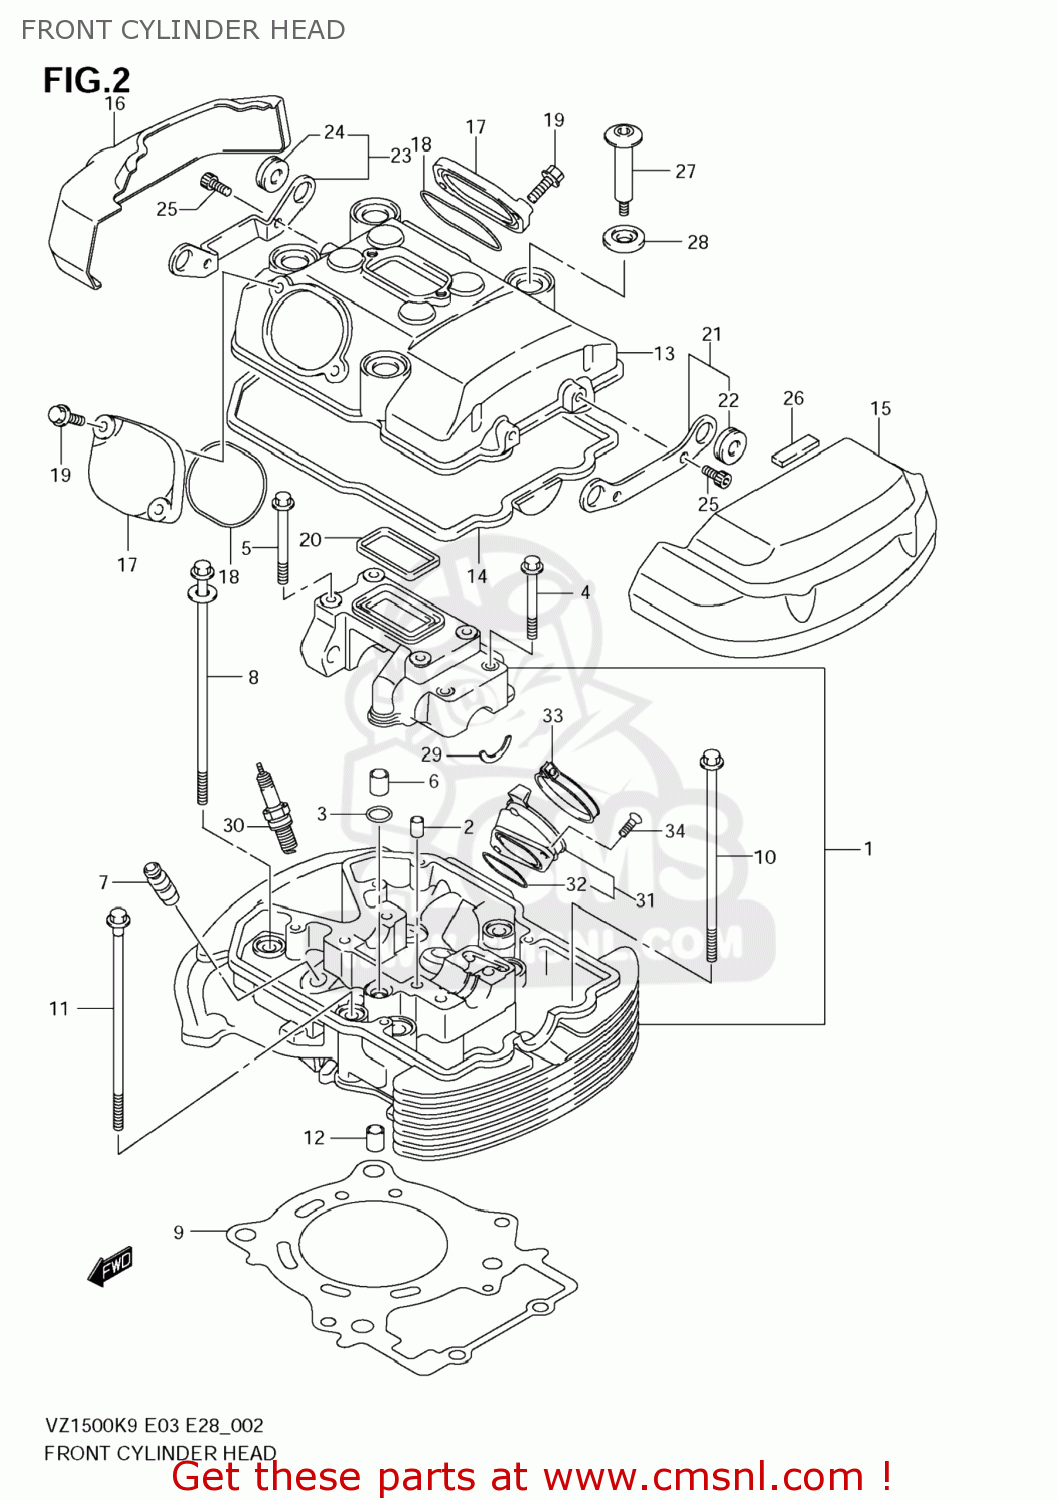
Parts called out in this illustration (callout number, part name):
1	HEAD ASSY,CYLINDER FR
2	PIN(6.2X8X11)
3	O RING(D:2.4,ID:10.8)
4	BOLT
5	BOLT
6	PIN
7	GUIDE,VALVE
8	BOLT,CYLINDER HEAD(L:190)
9	GASKET,CYLINDER HEAD FR (NAS)
10	BOLT(8X160)
11	BOLT(8X180)
12	PIN
13	COVER,CYLINDER HEAD
14	GASKET,CYL HEAD COVER NO.1 (NAS)
15	CAP,CYLINDER HEAD COVER NO.1
16	CAP,CYLINDER HEAD COVER NO.2
17	CAP,INSPECTION
18	O RING(D:2.4,ID:23)
19	BOLT
20	GASKET,CYL HEAD COVER NO.2 (NAS)
21	BRACKET,HEAD COVER CAP NO.1
22	CUSHION
23	BRACKET,HEAD COVER CAP NO.2
24	CUSHION
25	BOLT
26	CUSHION,PANEL NO.2
27	BOLT(7X57)
28	WASHER,CYL HEAD COVER
29	C RING
30	PLUG,SPARK(CR6E)
31	PIPE ASSY,INTAKE FR
32	O RING(D:2.4,ID:44.7)
33	CLAMP,INTAKE PIPE
34	BOLT(6X20.5)
